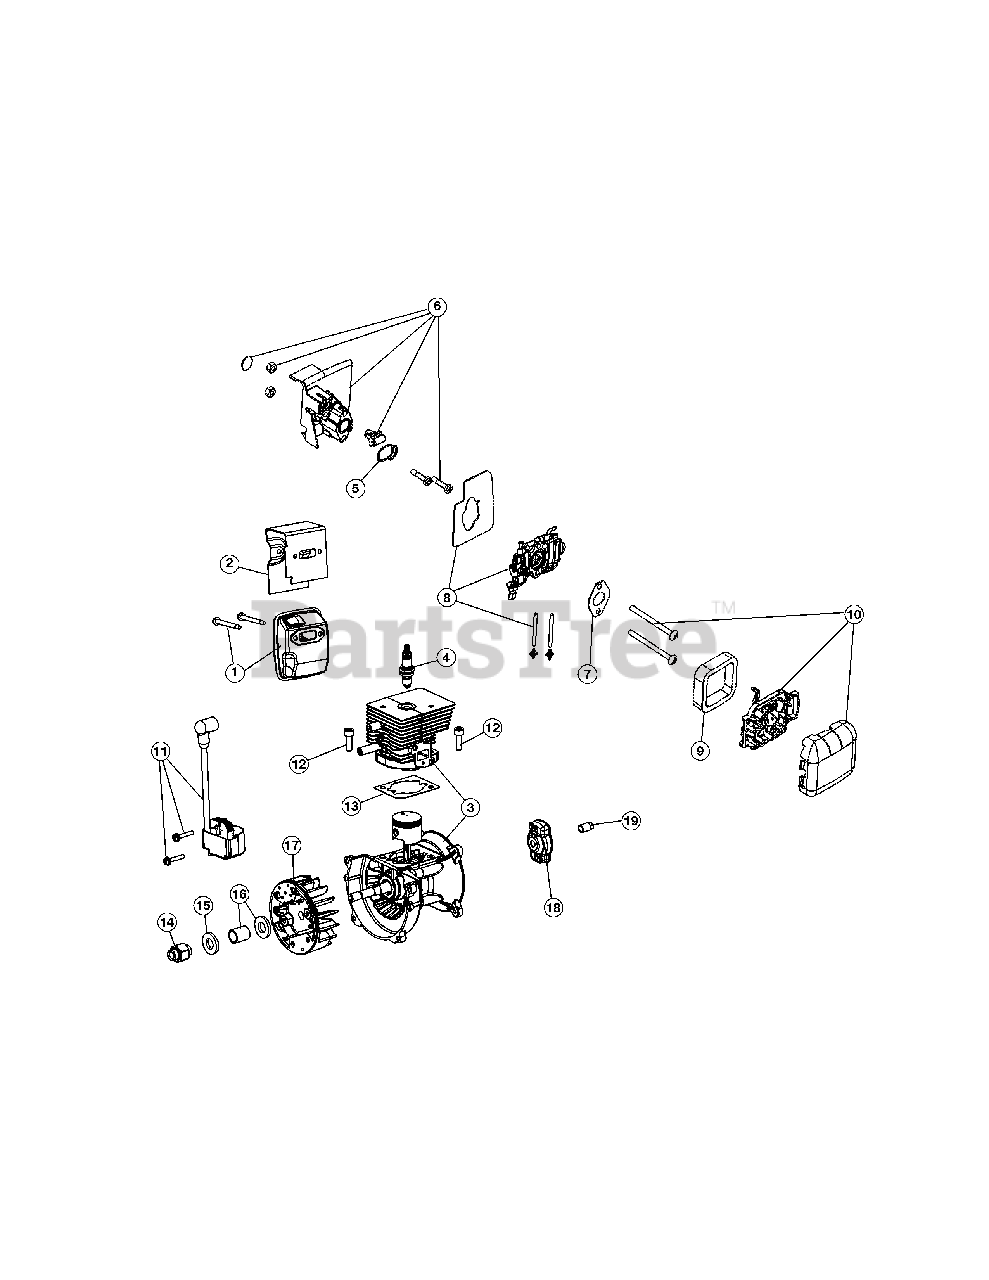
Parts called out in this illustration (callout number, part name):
1	Muffler Assembly (Incl Ref No. 2)
2	Muffler Gasket
3	Shortblock Assembly (Incl Ref No. 4 & 11-17)
4	Spark Plug
5	Insulator O-Ring
6	Insulator Assembly (Incl Ref No. 5)
7	Carburetor Gasket
8	Carburetor Assembly (Incl Ref No. 7)
9	Air Filter
10	Air Cleaner Assembly (Incl Ref No. 9)
11	Module Assembly
13	Cylinder Gasket
14	Flywheel Adaptor
15	Washer
16	Bushing
17	Flywheel Assembly
18	Pawl Assembly
19	Electric Start Adaptor
